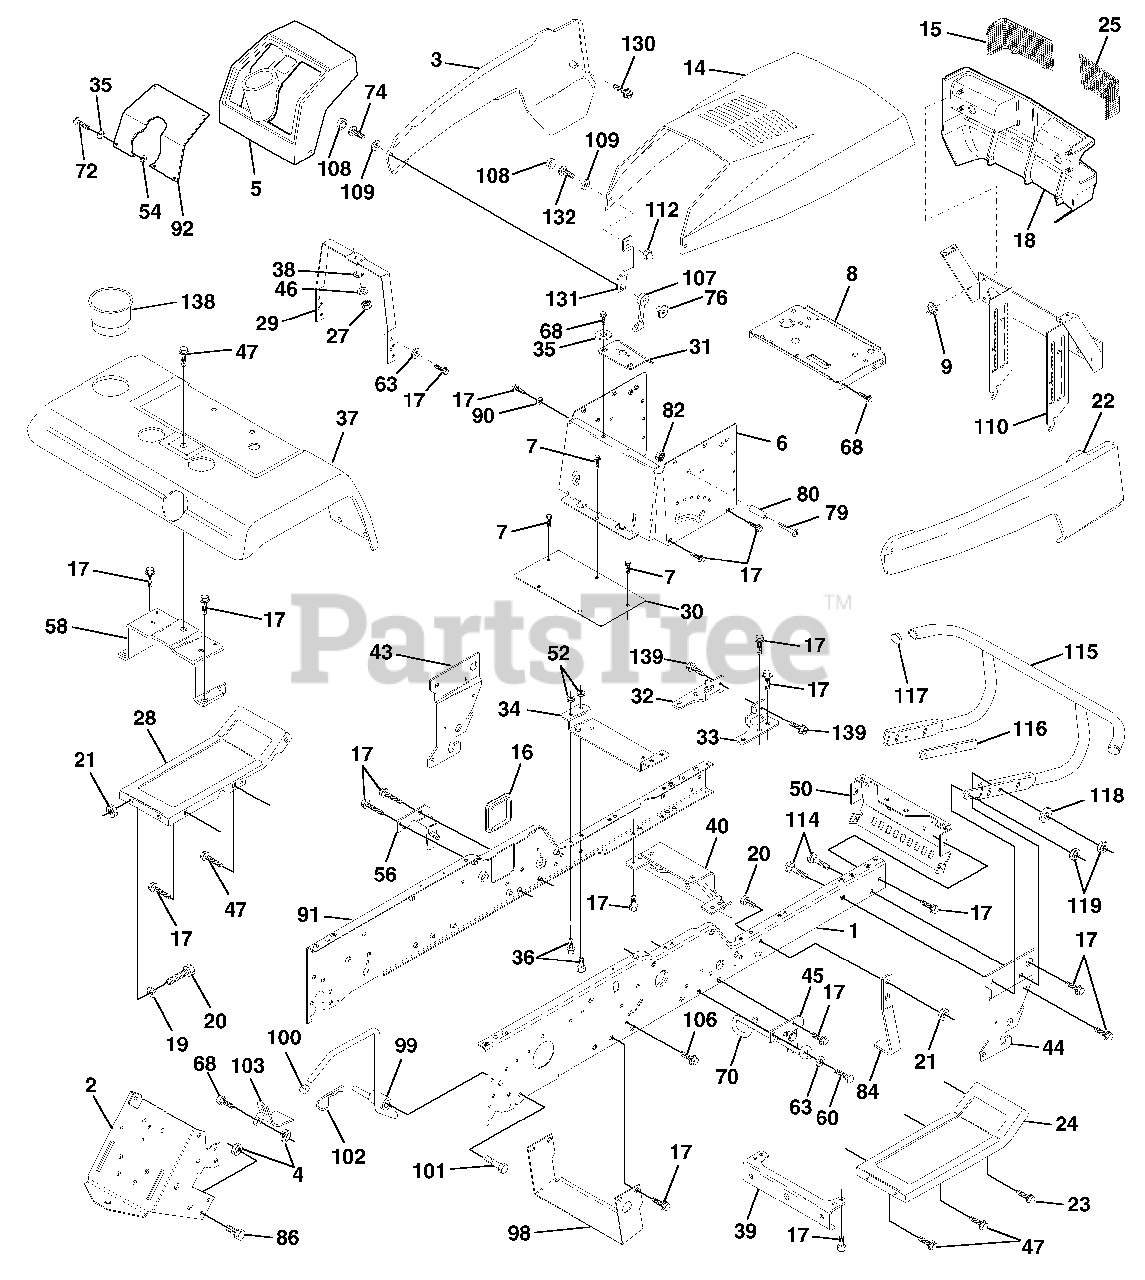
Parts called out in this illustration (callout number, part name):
1	Rail, Frame RH
2	Drawbar, Gt
3	Panel Asm., Side LH
4	Nut, Lock Hex 7/16 Unc
5	Dash, Plastic Black
6	Dash 1-PCS, Lower
7	Screw, Thd Cut 1/4-20 x 1/2
8	Support, Battery
14	Hood Asm., Pnt
15	Lens, Headlight LH
16	Cover, Access
17	Screw, Thdrol 3/8-16 x 3/4
19	Washer 13/32 x 13/16 x 12 Ga.
20	Bolt, Fin Hex 3/8-16 x 1
21	Nut, Crownlock 3/8-16 Unc
22	Panel Asm., Side RH
23	Screw Thdrol. 3/8-16 x 1 Ty-TT
24	Footrest, RH
25	Lens Headlight RH
27	Nut Fin Hex 1/4-20
28	Footrest, LH
29	Bracket, Support Dash
31	Brace, Support Steering
32	Bracket Asm., Frame Pivot Lh
33	Bracket Asm., Frame Pivot Rh
34	Bracket, Engine Support Rear
35	Washer 11/32 x 11/16 x 16 Ga.
36	Bolt, Fin Hex 5/16-18 x 3/4
37	Fender, Pnt.
38	Washer, Lock 1/4
39	Bracket, Axle Front
40	Bracket, Support Axle/Engine
43	Bracket, Spnsn Front Lh
44	Bracket, Spnsn Front Rh
45	Bracket Asm., Susp Chassis Rh
46	Washer 9/32 x 3/4 x 16 Ga.
47	Screw Thdrol 3/8-16 x 1/2
50	Bracket, Chassis Front
52	Locknut, Hex W/Ins 5/16-18 Unc
54	Nut 5/16-18
56	Bracket Asm., Susp Chassis Lh
58	Bracket Asm., Fender
60	Screw Thdrol 3/8-16 x 1-1/4
63	Washer 13/32 x 1 x 14 Ga.
68	Screw, Thdrol 5/16-18 x 1/2
70	Guide, Belt Mid Span
72	Screw, Mach Trhd 5/16-18 x 3/4
74	Screw, Machine #10-24
76	Nut, Weld #10-24
79	Screw, Machine #10-24 x 1/4
80	Spacer, Split
82	Nut #10-24
84	Stop, Over Center 44" 20/23" T. 94
86	Bolt, Fin Hex 7/16-14 Unc x 1
90	Washer, Lock External Tooth 3/8
91	Rail, Frame Lh
92	Plate, Silkscreen Dash
95	Push Nut, Nylon
98	Bracket Chassis Skid
99	Rod Asm. Bypass
100	Cap Brake Parking Red
101	Screw Thdrol. 3/8-16 x 1-3/4
102	Retainer Spring 1"
103	Bracket Lock Bypass
106	Screw Thdrol. Hex Hd Zinc Mur
107	Latch, Chute Blk
108	Cap, Snap Black
109	Cap, Washer Snap
110	Pivot Asm. Grille/Hood Husq. VGT
112	Nut, Acorn, Hex #10-24
114	Bolt, Carriage 3/8-16 x 1-1/4
115	Bumper Asm.
116	Bracket Extension Bumper
117	Plug Plastic
118	Washer 13/32 x 13/16 x 16 Ga.
119	Nut Crownlock 3/8-16 UNC
120	Washer 13/32 x 1 x 16 Ga.
130	Screw HWHD Hi-Lo #13-16 x 3/4
131	Bracket Support Hood/Panel YP
132	Screw Truss Hd. #10-24 x 3/8
138	Cupholder YTGT Grey
139	Bolt, Shoulder 5/16-18 TT
